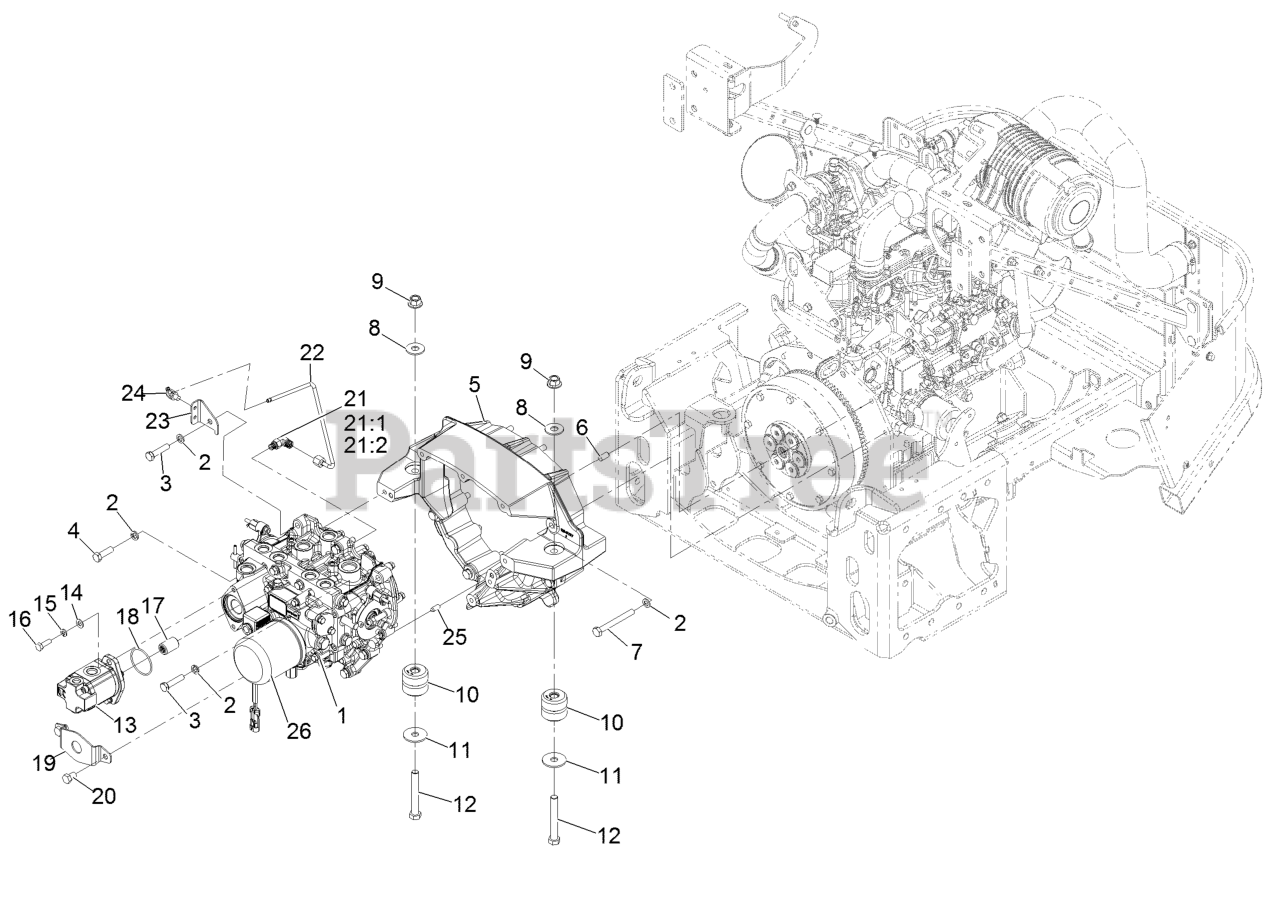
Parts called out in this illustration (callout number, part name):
1	Transmisson ASM
2	Washer-Lock
3	Screw-HH
4	Screw-HH M10-1.5 X 25Mm
5	Housing-Flywheel
6	Pin-Dowel
7	Screw-HH
8	Washer
9	Nut-Lock 1/2-13
10	Mount-Isolator
12	Screw-HH
13	HYD Gear Pump ASM
14	Washer-5/16 SAE
15	Washer-Lock 5/16
16	Screw-HH M8-1.25 X 25Mm
17	Coupler-Spline
19	Shield-Seal
20	Screw-HH
21	Fitting-Elbow, 90
21:1	O-Ring
21:2	O-Ring
22	Tube ASM
23	Support-Tube
24	Clip-Tie
25	Pin-Dowel
26	Filter-Oil, HYD
